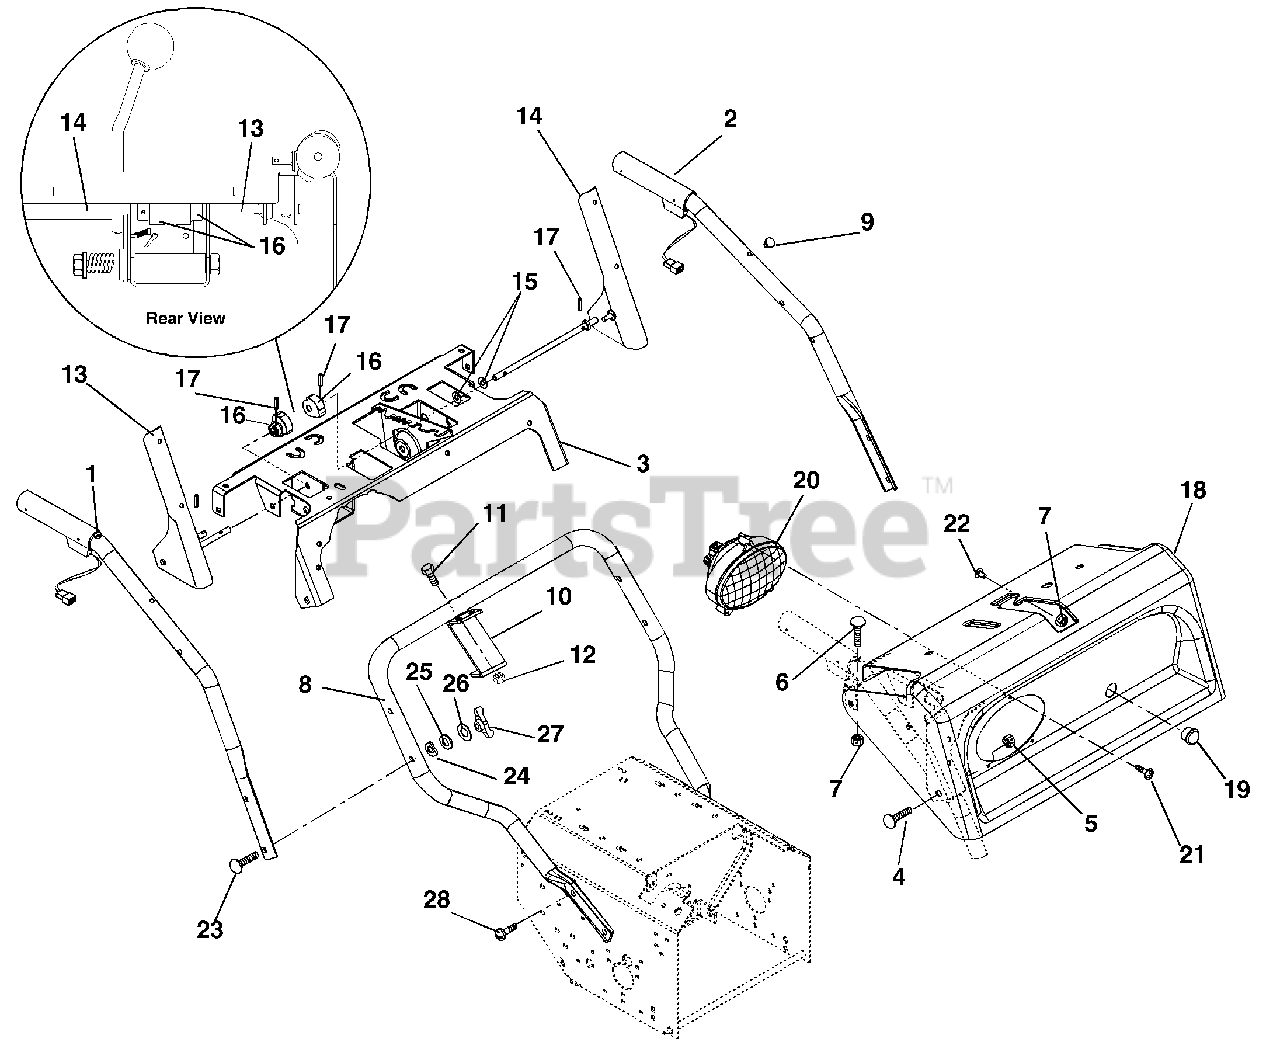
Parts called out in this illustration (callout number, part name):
1	HANDLEBAR, UPPER RH
2	HANDLEBAR, UPPER LH
3	PANEL, SUB
4	@BLT-RDHDSQNK .31-18X1.50 G5YZ
5	@NUT-LK-CTR .31-18 YWZC
6	BLT-RDHDXLSQNK.25-20X1.25 G5ZC
7	@NUT-LK-CTR .25-20 YWZC
8	HANDLEBAR, LOWER
10	BRACKET, CABLE SUPPORT
11	@BLT-HEX .25-20X1.50 GR5 YWZC
12	@NUT-LK-CTR .25-20 YWZC
13	LEVER, RH-COATED
14	LEVER, LH-COATED
15	@WSHR-FL-STL.344X.688X.065YWZC
16	CAM, INTERLOCK
17	PIN-ROLL .125X.75
18	PANEL W/DECAL - 936
19	SNAP BUSHING
20	HEADLAMP, OVAL W/ 1156 BULB
21	SCR-TAP 10-16X.75 HI-LO PPH
22	BLT-RDHDSQSHNK.25-20X.50 YWZC
23	@BLT-RDHDSQNK .31-18X2.25 G5YZ
24	WASHER,SADDLE-.320 X.937 X.062
25	WSHR-LK .312X.097 HVY YWZC
26	WSHR-FL-STL .328X.875X.062YWZC
27	KNOB - WING .312-18 UNC
28	BLT-SERHFWH .38-16X.75 YWZC
